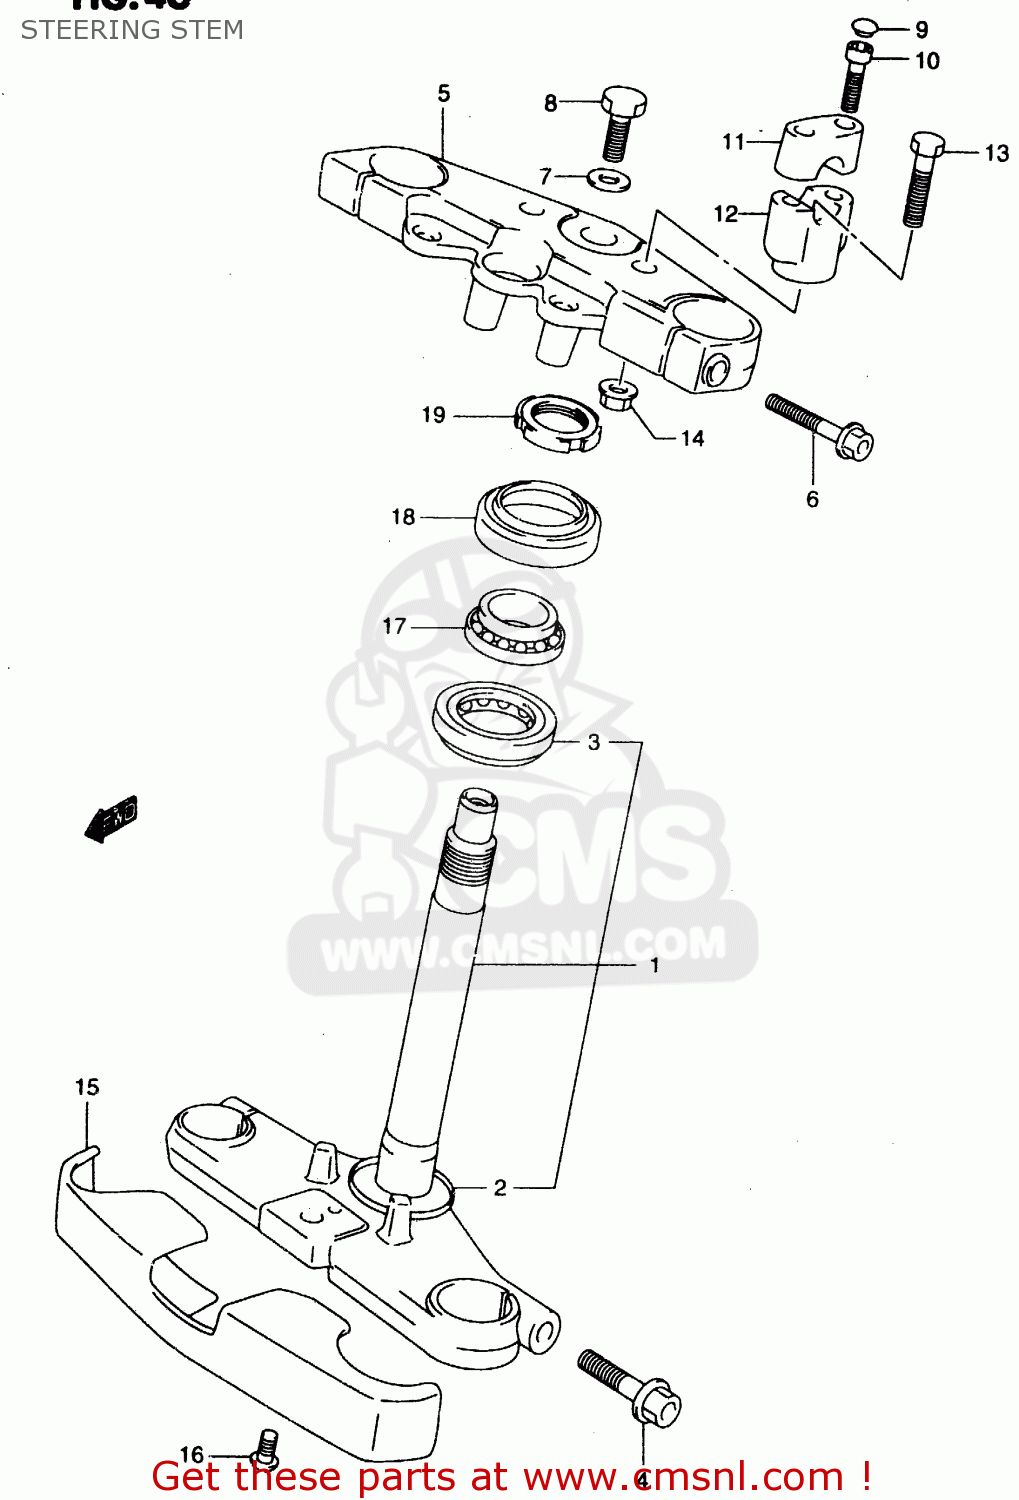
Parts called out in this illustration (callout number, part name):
1	STEM,STEERING
2	SEAL,STEERING LWR
3	BEARING(30X55X17)
4	BOLT
5	HEAD,STEERING STEM
6	BOLT
7	WASHER,STEERING STEM
8	BOLT,STEERING STEM HEAD
9	CAP(OD:11)
10	BOLT
11	HOLDER,HANDLE UPR
12	HOLDER,HANDLE UNDER
13	BOLT
14	NUT
15	COVER,FR FORK UNDER
16	SCREW(6X16)
17	BEARING(25X47X15)
18	DUST SEAL,STEERING UPR
19	NUT,STEERING STEM(25X44X10)
